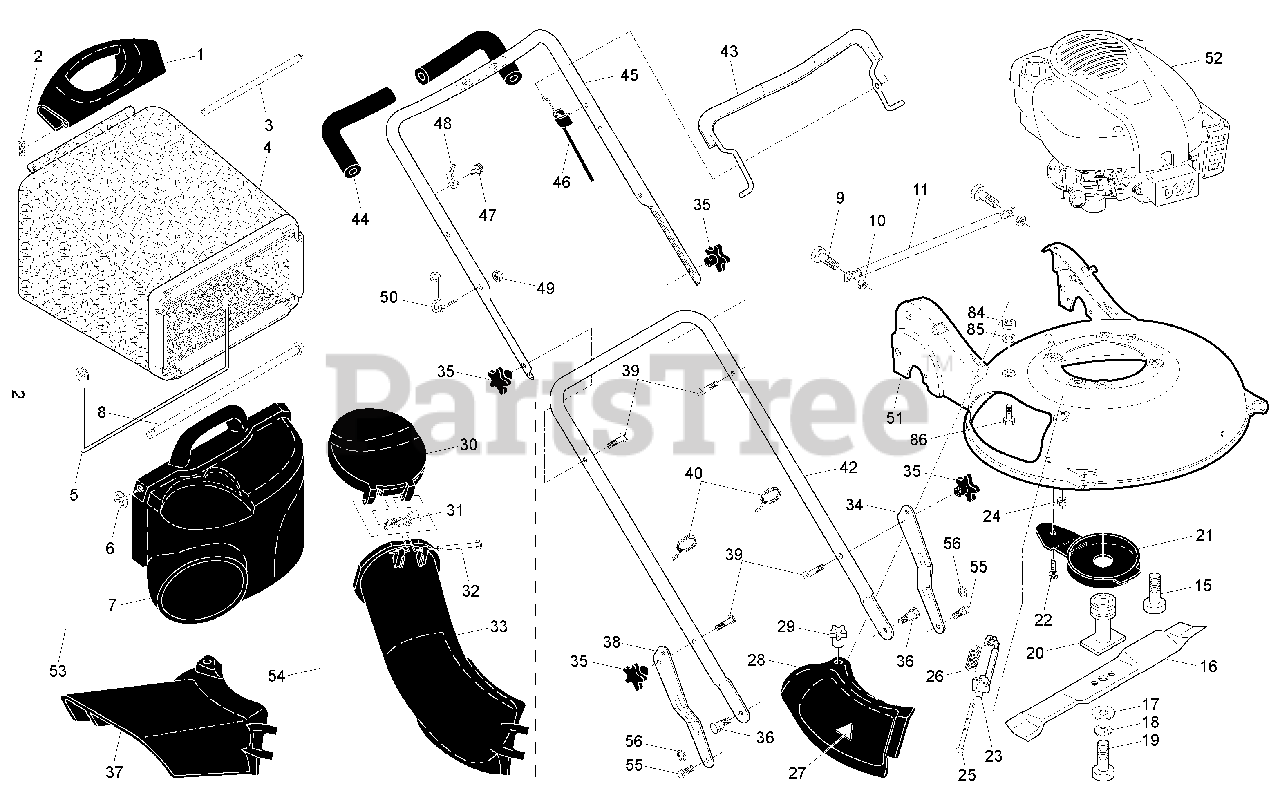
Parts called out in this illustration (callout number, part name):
1	Handle, Grassbag, Rear
2	Hairpin Cotter
3	Rod, Rear Handle, Grassbag
5	Frame, Grassbag
7	Door, Grassbag
8	Rod, Pivot
9	Bolt, Carriage 1/4-20
10	Nut, Hex, Nylock 1/4-20
11	Foot Guard
15	Bolt, Engine Mounting
16	Blade, 21"
17	Washer, Hardened
18	Washer, Lock
19	Bolt, Hex Head, Grade 8
20	Adapter, Blade
21	Debris Shield
22	Screw, Hex Head, Serrated
23	Mounting Bracket, Mulcher Door
25	Rod, Hinge
26	Spring, Mulcher Door
27	Decal, Danger
28	Mulcher Door
30	Door, Discharge Chute
31	Spring, Door, Discharge Chute
32	Rod, Door, Discharge Chute
33	Discharge Chute, Plastic
34	Adjustment Bracket, Lower Handle, LH
35	Knob, Star
36	Bolt, Shoulder
37	Deflector, Discharge
38	Adjustment Bracket, Lower Handle, RH
39	Bolt, Handle
40	Wire Tie
42	Handle Assembly, Lower
43	Bail, Control
44	Grip, Foam
45	Handle Assembly, Upper
46	Cable, Engine Zone Control
48	Bracket, Upstop
49	Nut, Hex
50	Rope Guide
51	Kit, Housing
52	Engine, Briggs & Stratton, Model Number 100602- 2980-EA (Order parts from Engine Manufacturer)
53	Grassbag Assembly, Complete
54	Discharge Chute Assembly, Complete
55	Stud, Shoulder T45
84	Locknut, Hex
85	Washer, Lock 3/8
86	Bolt, Carriage 1/4-20 x 7/8
